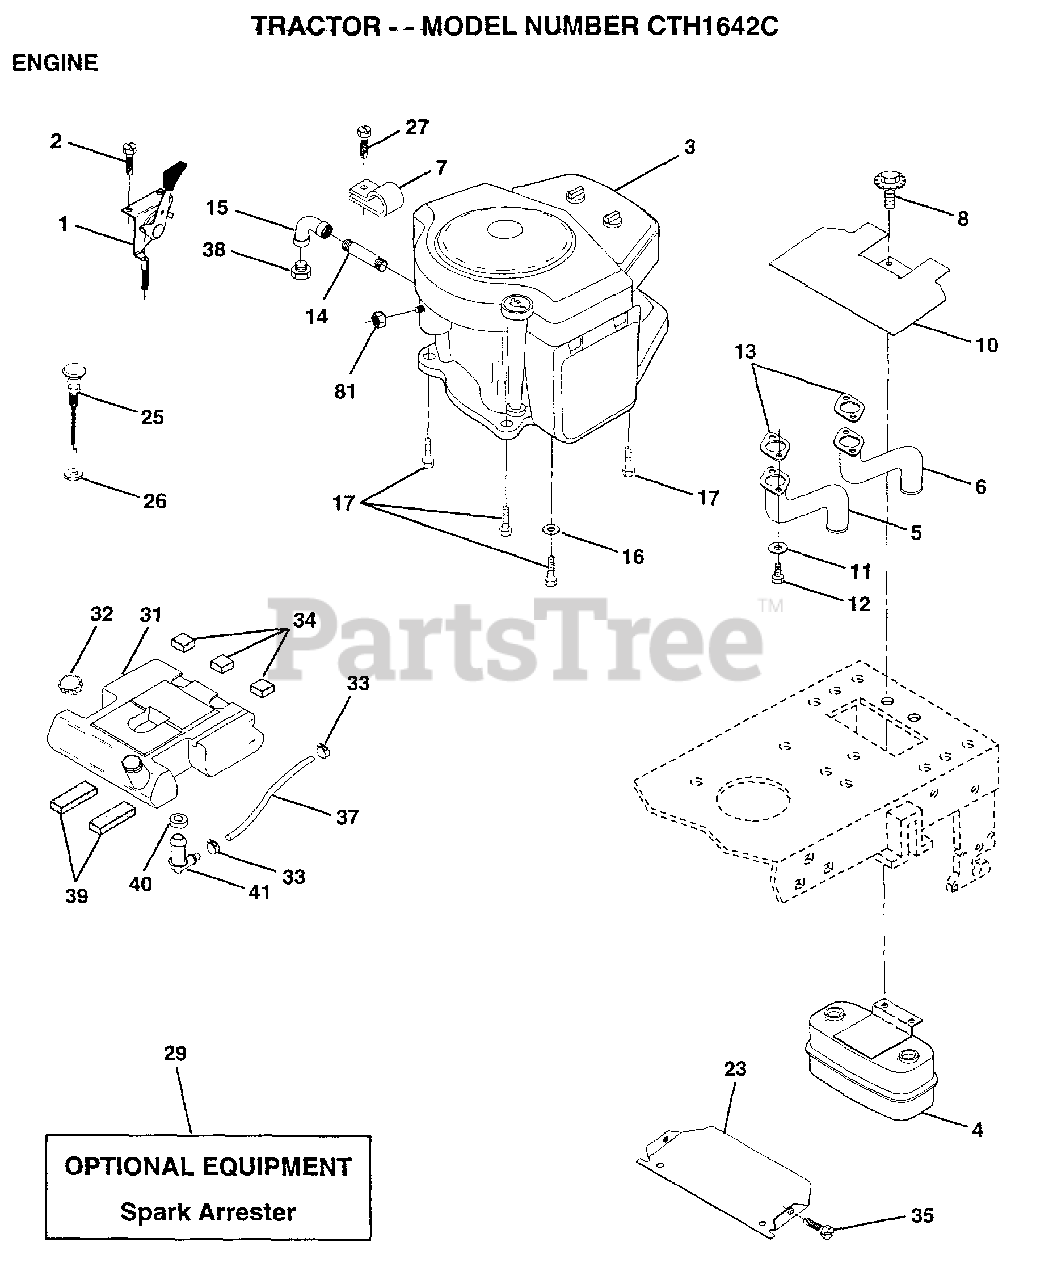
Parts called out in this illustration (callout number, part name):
2	SCREW LT
4	MUFFLER.TW.LOTONE
5	EXHAUST.B&S.18.LH
6	EXHAUST.B&S.18.RH
7	CLAMP.TUBE.DBL.EN
8	BOLT.5/16-18.UNC
10	SHIELD.HEAT.
11	LOCKWASHER
13	GASKET MUFFLER
14	PIPE NIPPLE LT
15	ELBOW
16	LOCKWASHER
17	SCREW LT
25	"CONTROL.CHOKE.51"""
26	"NUT,KEPS 3/8-24IM"
27	"SCREW-TT,10-32 FL"
31	TANK FUEL REAR
32	CAP ASM FUEL
33	HOSE CLAMP
34	PAD-SPACER LT
35	SCREW
37	FUEL LINE T
39	PAD IDLER TI
40	BUSHING OUTLET T
41	STEM.TANK.FUEL
81	NUT
